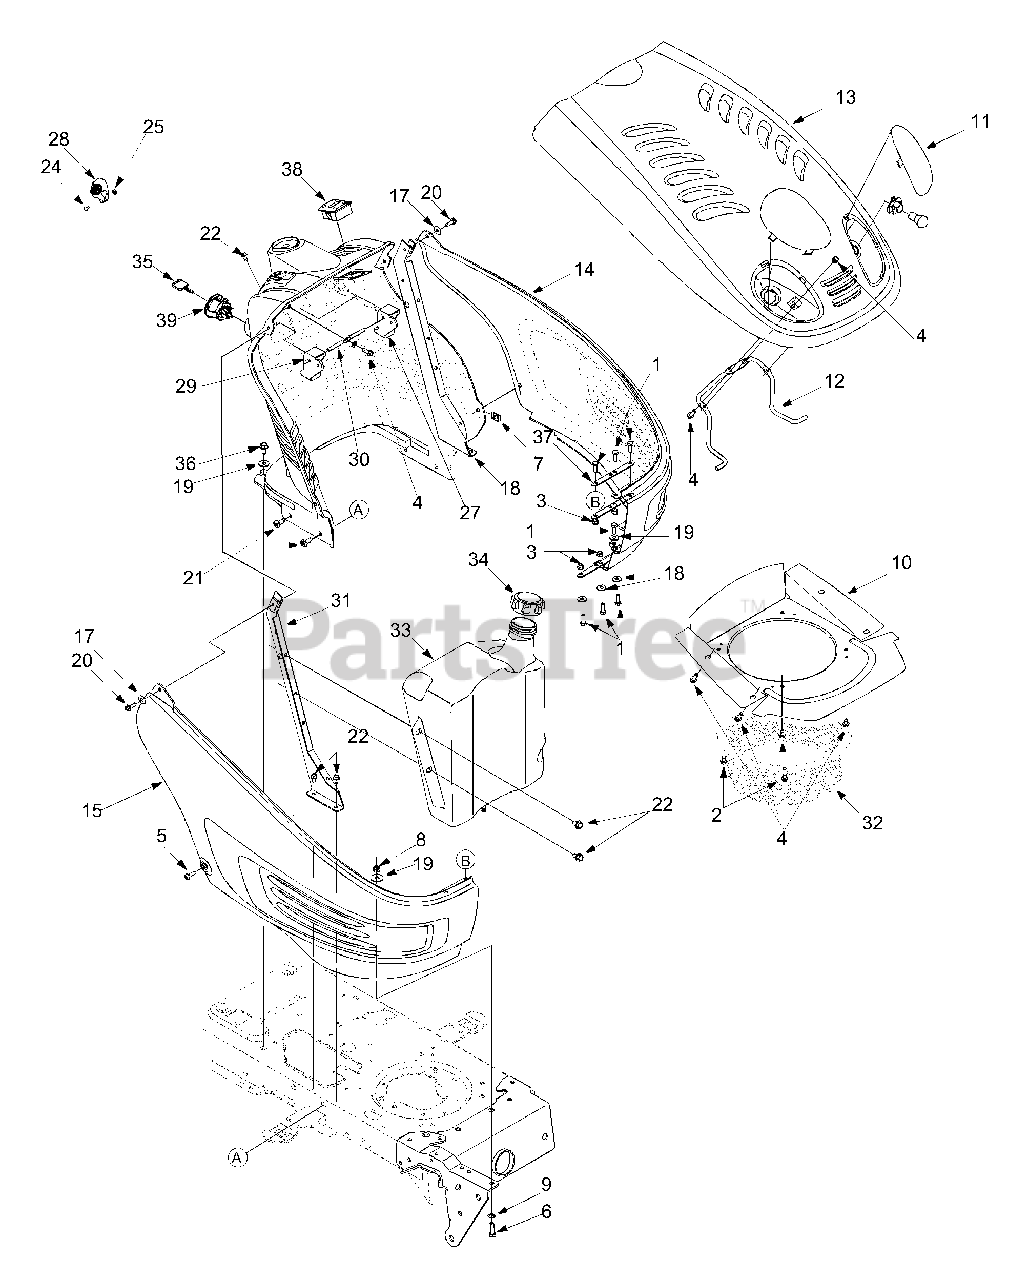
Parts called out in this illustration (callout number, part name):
1	Hex Cap Screw, 1/4-20 x .75
2	Self-tapping Screw, 1/4-20 x .5
3	Hex Lock Nut, 1/4-20
4	Self-tapping Screw, 1/4-15 x .75
5	Pan Phillips Screw, 1/4-20 x .75
6	Hex Cap Screw, 5/16-18 x 1.0
7	U-type Speed Nut, 1/4-20
8	Lock Nut, 5/16-18
9	Speed Nut
11	RH Headlight Lens
12	Hood Support Rod
13	Hood
14	LH Side Panel
15	RH Side Panel
16	Lock Washer, 1/4
17	Flat Washer, .283 x .75 x .030
19	Flat Washer, .349 x 1.0 x .063
20	Self-tapping Screw, 1/4-20 x 1.25
21	Self-tapping Screw, 5/16-18 x .75
22	Self-tapping Screw, 1/4-20 x .50
23	Torx Self-tapping Screw, 1/4-14 x .625
24	Torx Screw, #8-32 x .375
25	Hex Nut, 8-32
26	Dash Panel
27	Parking Brake Button
28	Throttle Control Lever
29	Cruise Control Button
30	Brake/Cruise Pivot Rod
33	Fuel Tank, 3-gallon
34	Fuel Cap
35	Ignition Key w/ plastic cover
36	Self-tapping Screw, 5/16-18 x .75
39	Ignition Switch
40	Headlight Assembly
